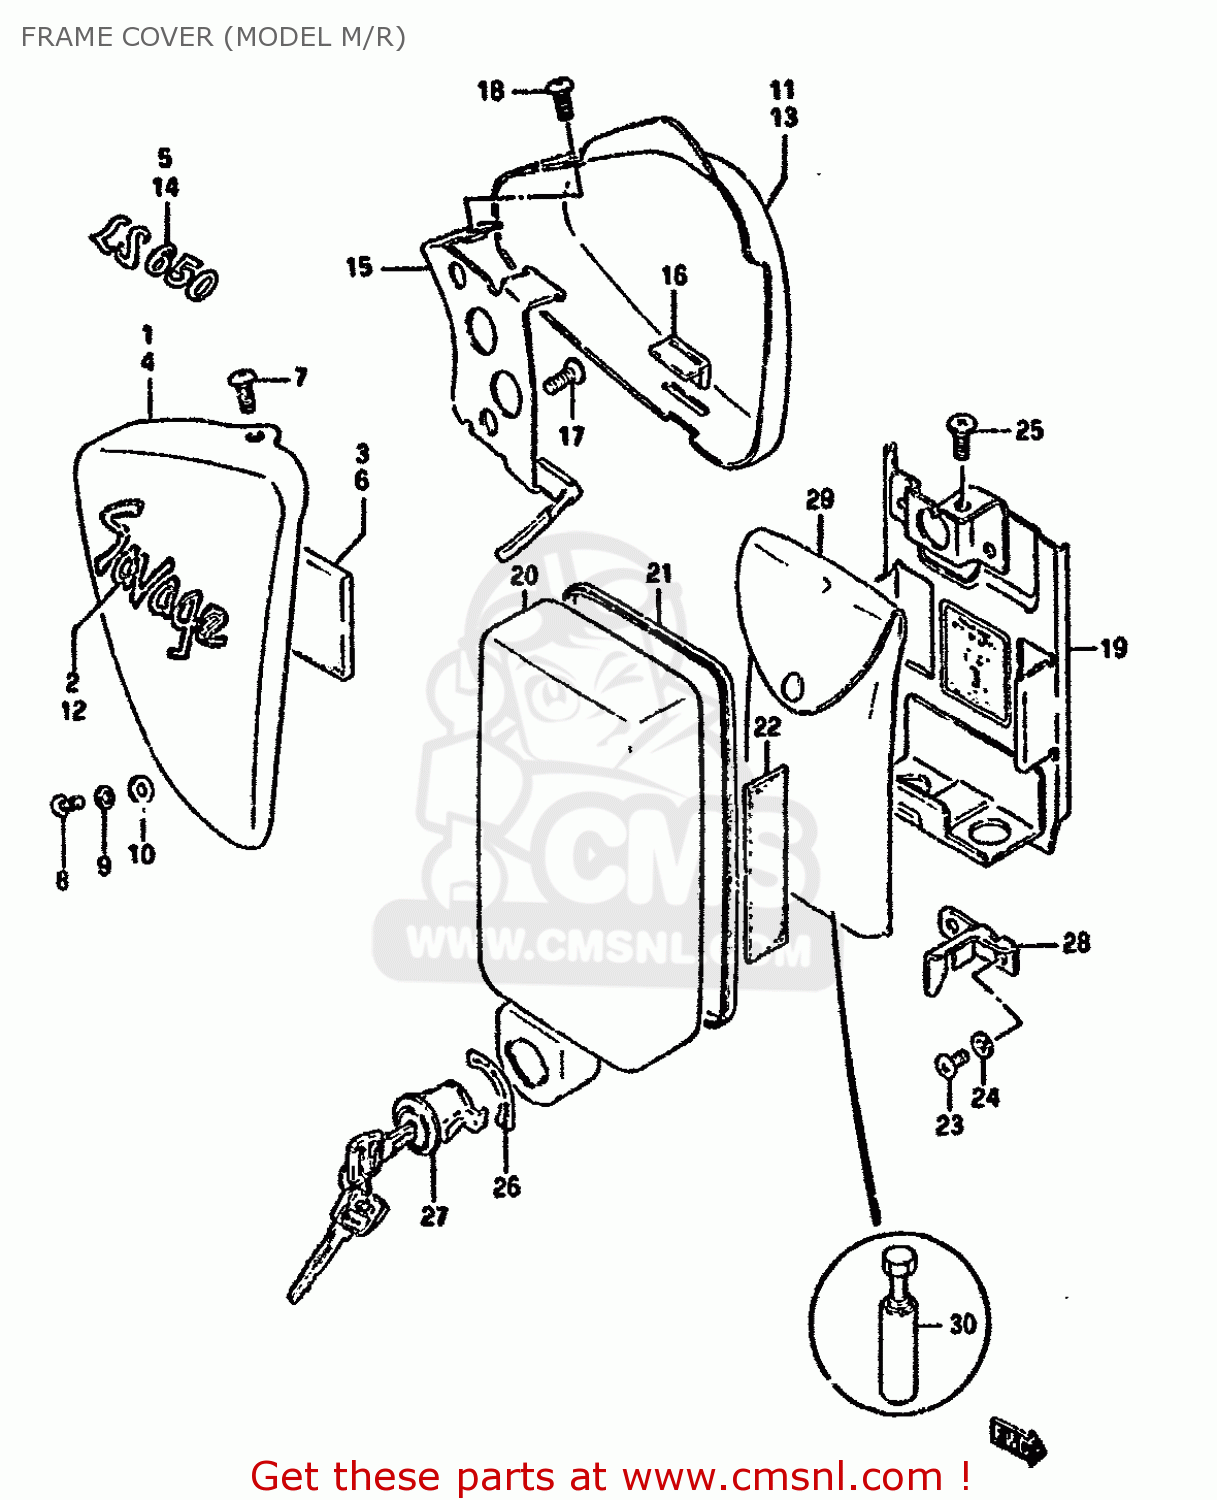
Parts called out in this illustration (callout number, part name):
1	COVER,FRAME,RH
2	EMBLEM,FRAME COVER
3	PAD
4	COVER,FRAME RH (BLACK)
5	EMBLEM
6	PAD
7	SCREW
8	SCREW
9	WASHER,LOCK
10	WASHER,5MM
11	COVER ASSY,FRAME,L(BLACK)
12	EMBLEM,FRAME COVER
13	COVER,FRAME LH
14	EMBLEM
15	BRACKET,FRAME COVER,L
16	CUSHION,FRAME COVER
17	SCREW
18	SCREW 5X12
19	HOLDER,TOOL
20	COVER COMP,TOOL HOLDER
21	MOLDING
22	PROTECTOR(20X90)X2
23	SCREW
24	WASHER,5MM
25	SCREW
26	LABEL,TOOL LOCK COVER
27	LOCK SET,TOOL HOLDER
28	PLATE,TOOL HOLDER LOCK
29	TOOL ASSY
30	GAUGE ASSY,TENSION
